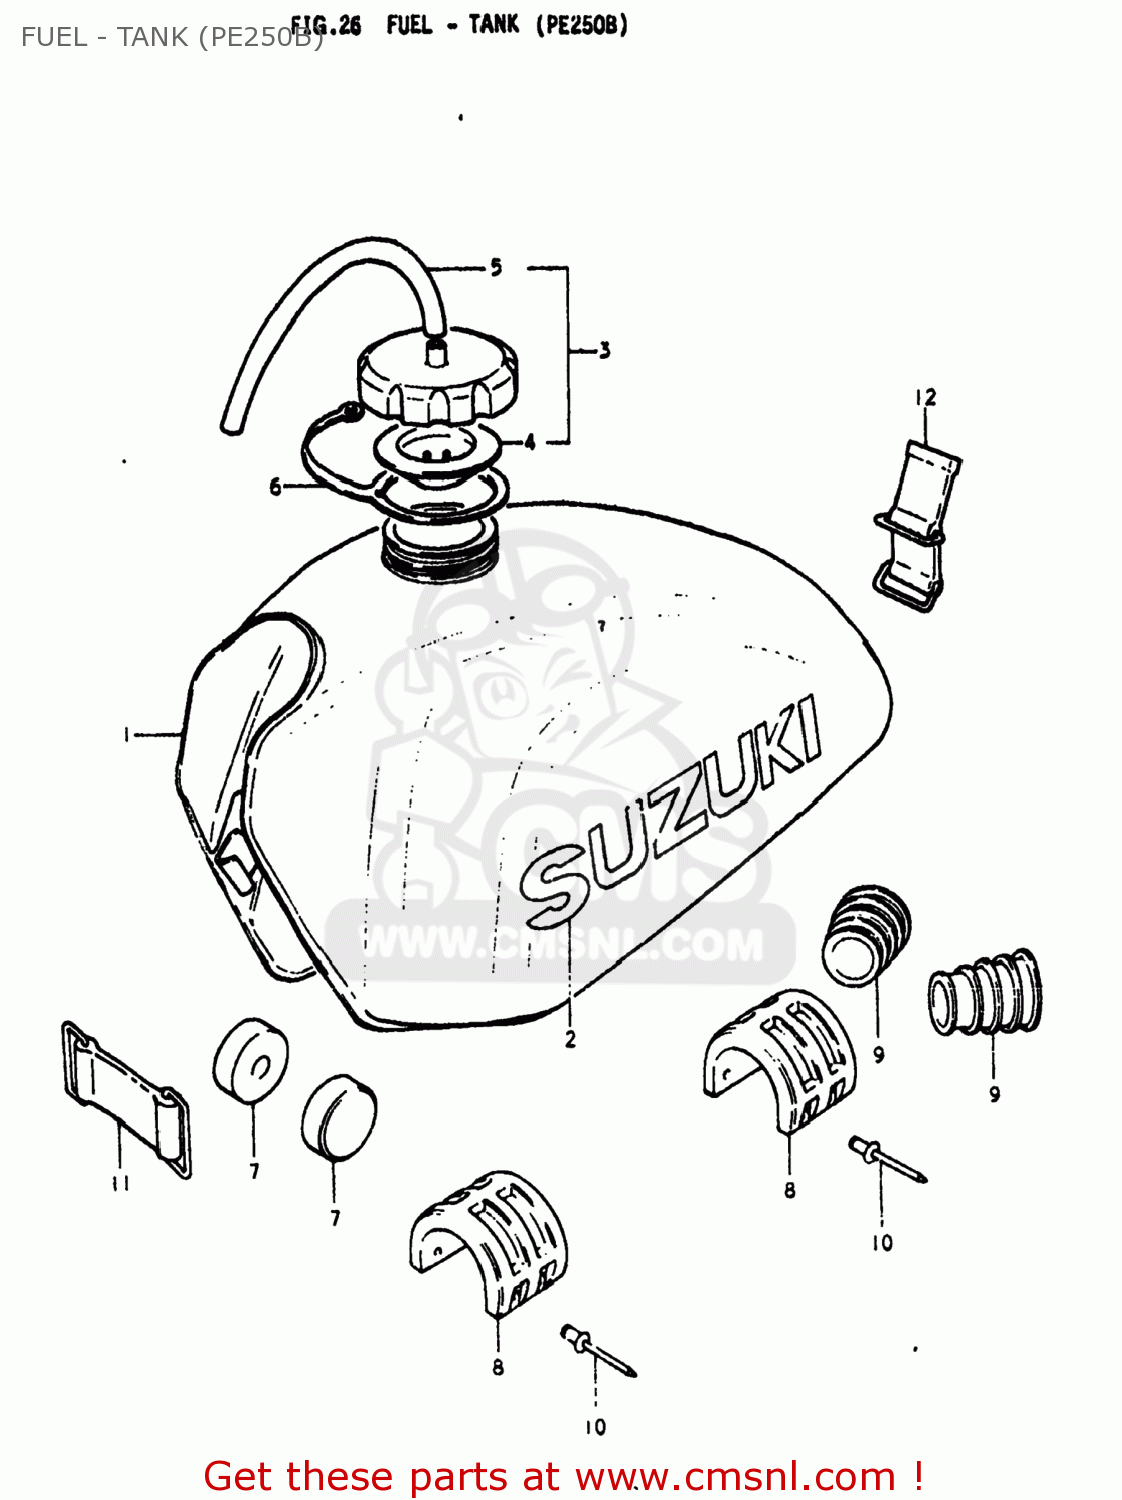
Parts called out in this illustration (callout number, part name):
1	TANK ASSEMBLY,FUEL
2	EMBLEM
3	CAP ASSEMBLY,FUEL TANK
4	GASKET,FUEL TANK CAP (NAS)
5	HOSE
6	BAND,FUEL TANK CAP
7	CUSHION
8	CUSHION,FUEL TANK,CENTER
9	CUSHION,FUEL TANK,FRONT
10	RIVET
11	BAND
12	BAND
